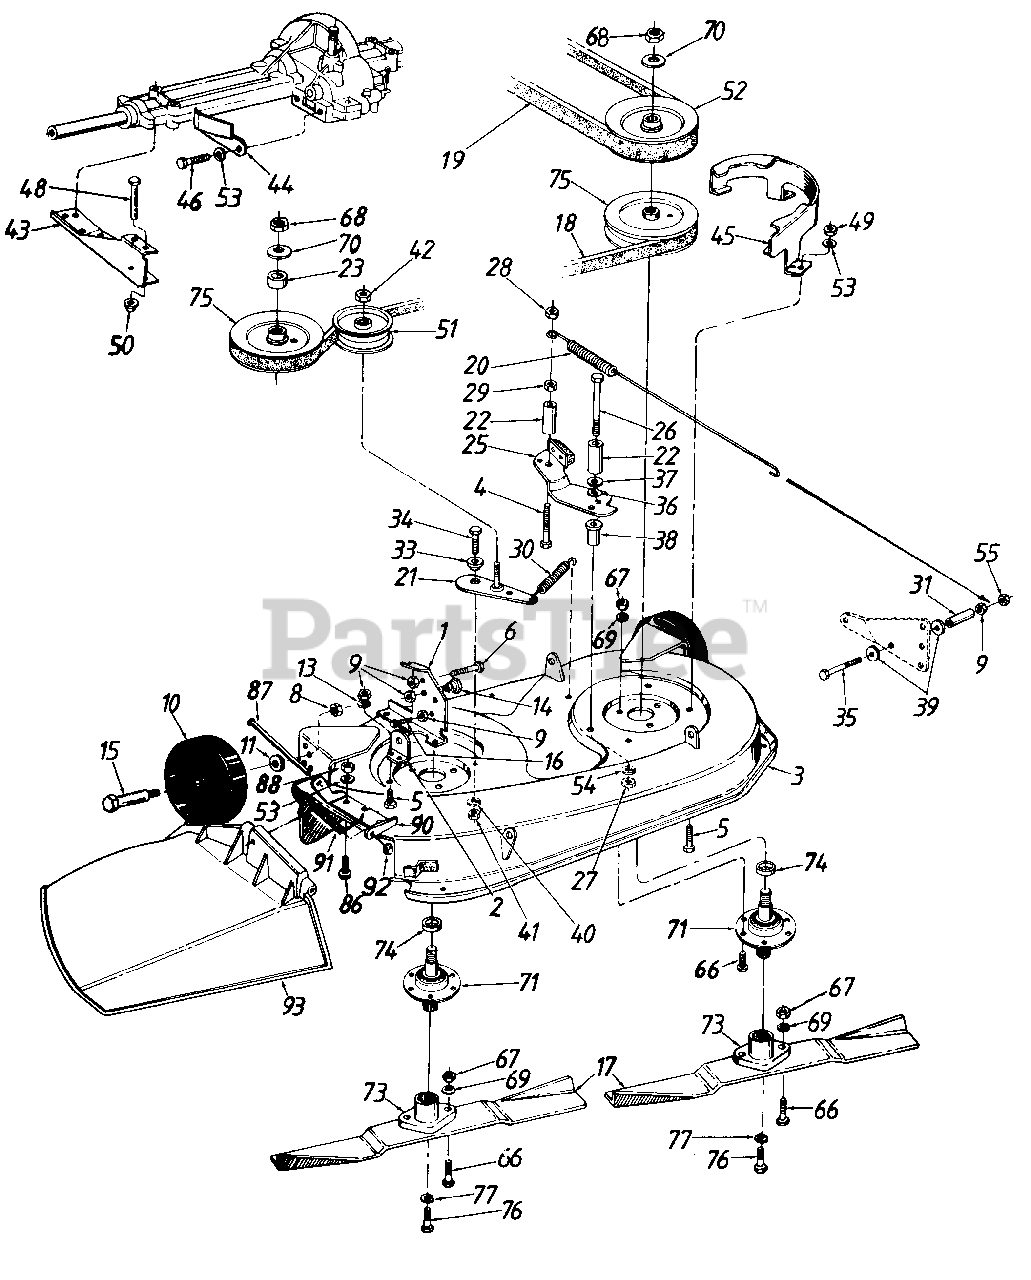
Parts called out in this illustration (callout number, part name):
1	Deck Engagement Brkt.
2	Rear Deck Brkt.-R.H.
3	32" Deck Ass'y.
4	Hex Bolt 1/4-28 x 1.75" Lg.
5	Hex Bolt 1/4-20 x .62" Lg.
6	Hex Wash. Hd. Scr. 1/4-20 x 1.5" Lg.
8	Hex L-Nut 3/8-16 Thd.
9	Hex Nut 1/4-20 Thd.
10	Deck Wheel
11	Bell-Wash. .38" I.D. x .88"
13	L-Wash. 1/4" I.D.
14	Shld. Bolt .500" Dia. x .215"
15	Shld. Bolt .498" Dia. x 1.53"
16	Hex Tap Scr. 1/4-20 x .75" Lg.
17	High-Lift Blade 3" x 16.28"
18	V-Belt
19	V-Belt
20	Extension Spring 15-5/8" Lg.
21	Idler Brkt. Ass'y.
22	Spacer 5/16" I.D. x 1/2" O.D. x 31/32"
23	Spacer .752" I.D. x 1.25" O.D.
25	Deck Brake Brkt. Ass'y.
26	Hex Bolt 5/16-18 x 3.25" Lg.
27	Hex Nut 5/16-24 Thd.
28	Hex L-Nut 1/4-28 Thd.
29	Hex Nut 1/4-28 Thd.
30	Extension Spring 4.35" Lg.
31	Spacer 1/4" I.D. x 3/8" O.D. x 1-5/16" Lg.
33	Shoulder Spacer
34	Hex Bolt 3/8-16 x 1" Lg.
35	Hex Bolt 1/4-20 x 2.5" Lg.
36	Wave Washer .53" I.D.
37	Shld. Spacer .51" I.D. x .27"
38	Spacer .312" I.D. x 1.46" Lg.
39	Flat Wash. 1/4"
40	L-Wash. 3/8" I.D.
41	Hex Nut 3/8-16 Thd.
42	Hex L-Nut 3/8-24 Thd.
45	Belt Guard Deck-R.H.
46	Hex Bolt 1/4-20 x .62" Lg.
48	Pin 1/4" Dia. x 2.5" Lg.
49	Hex Nut 1/4-20 Thd.
50	Cap Speed Nut 1/4" Rod
51	Flat Idler Pulley
52	5" Dia. Pulley
53	Bell-Wash. .265" I.D.
54	Bell-Wash. 5/16" I.D.
55	Hex L-Nut 1/4-20 Thd.
66	Hex Bolt 5/16-24 x 1" Lg.
67	Hex Nut 5/16-24 Thd.
68	Hex Jam Nut 5/8-18 Thd.
69	L-Wash. 5/16" I.D.
70	Bell-Wash. 5/8" I.D.
71	Blade Spindle Ass'y. Comp.
73	Blade Adapter
75	5" Dia. Pulley
76	Hex Bolt 3/8-24 x 1.0" Lg.
77	L-Wash. 3/8" I.D. H.D.
86	Truss.-Mach. Scr. 1/4-20 x .75" Lg.
87	Hinge Pin
88	Hex Nut 1/4-20 Thd.
90	Hinge Mtg. Brkt.
91	Torsion Spring
92	Cap Speed Nut 1/4" Rod
93	Chute Ass'y. Comp.
